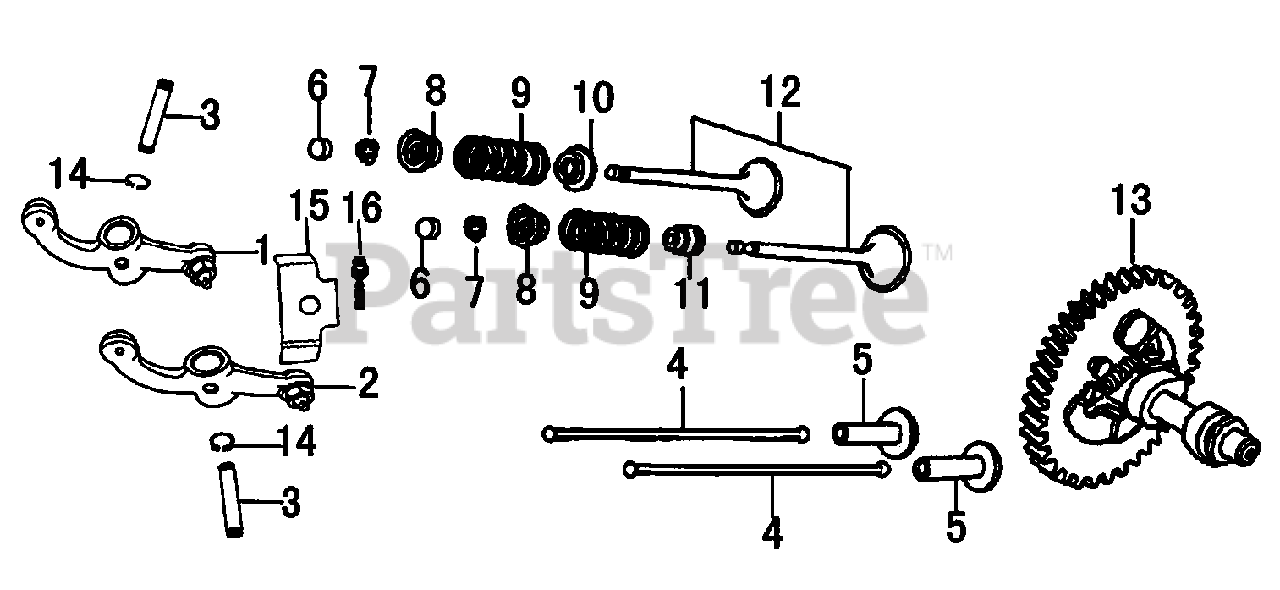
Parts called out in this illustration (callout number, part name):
1	ROCKER ARM ASSY.
2	ROCKER ARM ASSY.
3	SHAFT, VALVE ROCKER
4	ROD, PUSH
5	LIFTER, VALVE
6	ROTATOR, VALVE
7	KEEPER, VALVE
8	RETAINER, VALVE SPRING
9	SPRING, VALVE
10	SEAT, VALVE SPRING
11	SEAL, VALVE STEM
12	VALVE SET
13	CAMSHAFT ASSY
14	CIRCLIP ROCKER SHAFT
15	RETAINER, ROCKER ARM SHAFT
16	BOLT, FLANGE 6X12
